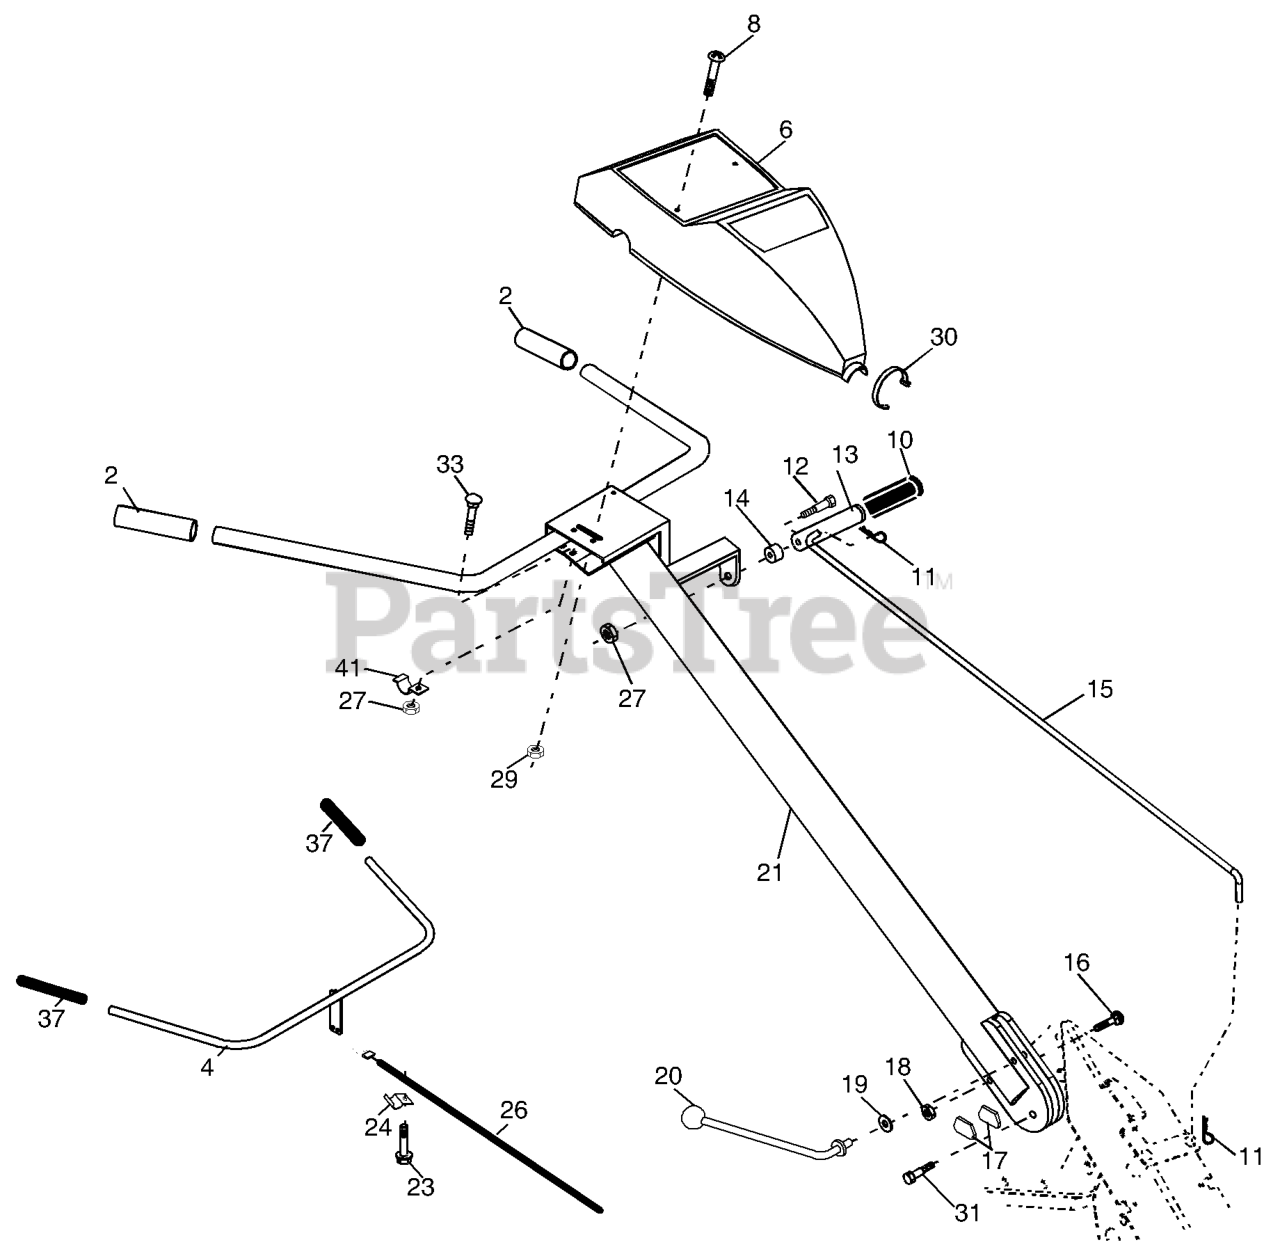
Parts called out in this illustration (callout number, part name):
2	KIT.GRIP.HANDLE.5.00.BLK.VINYL
4	CONTROL BAR ASSY
6	RP PANEL, CONTROL
8	SCREW.PNHD.10-24
10	GRIP T
11	RETAINER M
12	SHOULDER BOLT ST
13	HANDLE.SHIFT.TILLER
14	GROMMET.RUBBER.CRT.TILLER
15	SHIFT ROD CRT
16	BOLT D
17	LOCK.HANDLE.CRT
19	WASHER CRT
20	LEVER.LOCK.CRT
21	REPL BY 532 1805-17
23	TAPPING SCREW
24	CONDUIT.CLIP.PLATED
26	CABLE.CLUTCH
27	NUT T
29	NUT **
30	TIE CABLE CRT
31	BOLT.PIVOT
33	BOLT
37	GRIP BAR CRT(1)
41	CLAMP.BAR.CRT.BLACK
